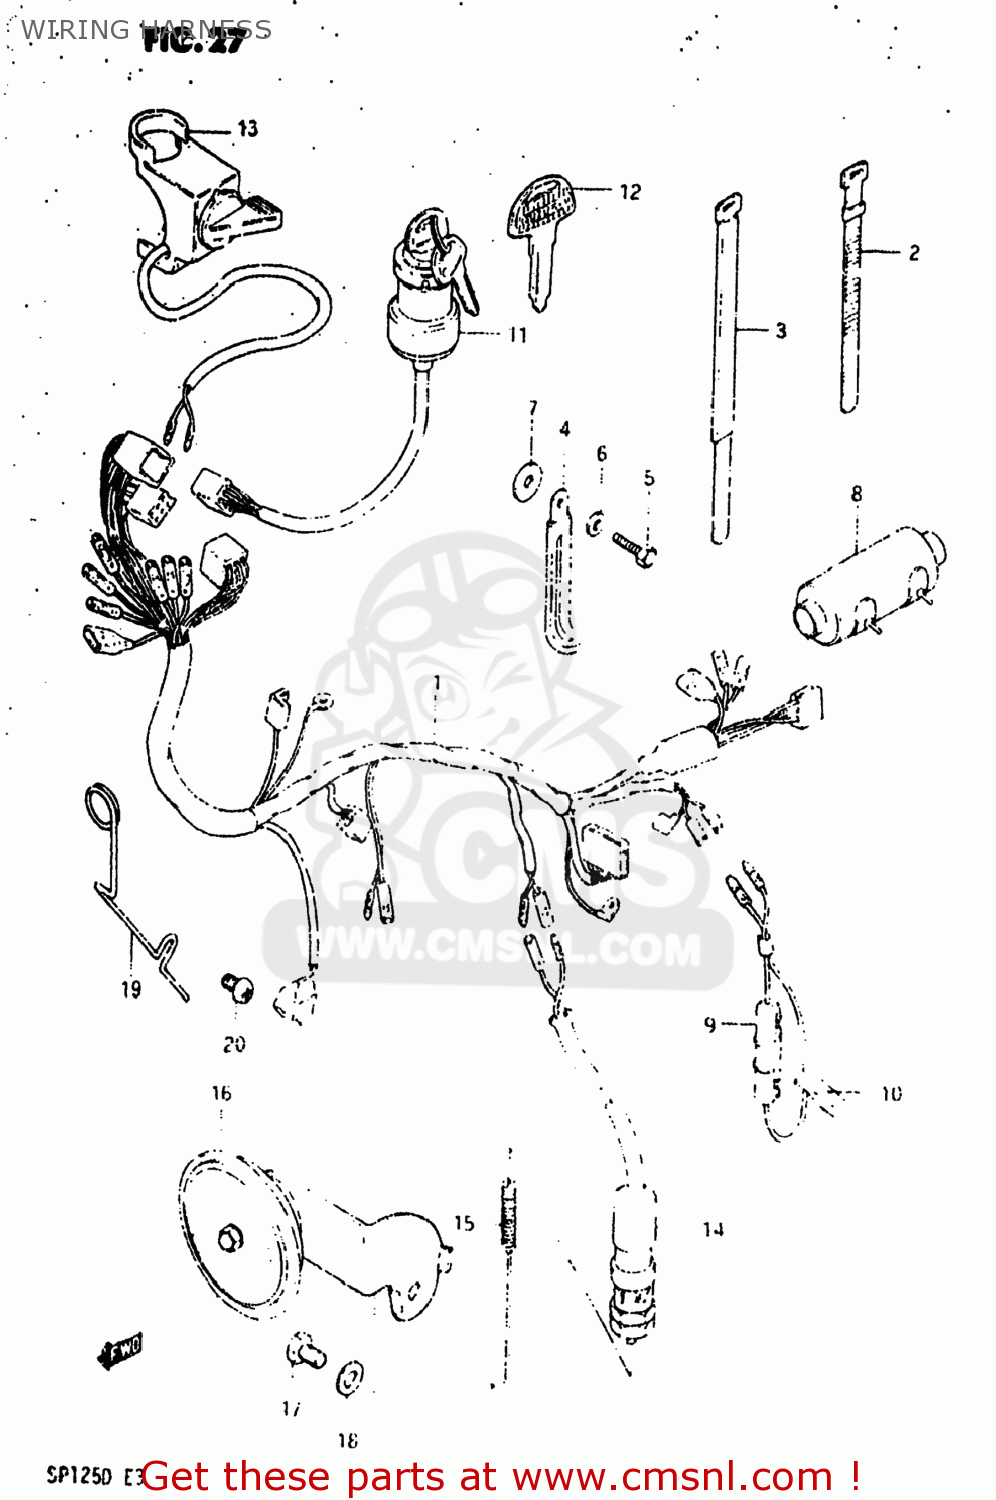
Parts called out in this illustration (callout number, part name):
1	HARNESS,WIRING
2	CLAMP(L:120)
3	CLAMP
4	CLAMP
5	BOLT, UPPER
6	WASHER
7	WASHER
8	BOOT,WIRING HARNESS
9	BOX ASSEMBLY,FUSE
10	FUSE(15A)
11	SWITCH ASSEMBLY,IGNITION
12	KEY,BLANK
13	SWITCH ASSY,ENGINE STOP
14	SWITCH ASSEMBLY,STOP LAMP
15	SPRING
16	HORN ASSEMBLY
17	BOLT
18	WASHER
19	GUIDE,TACHOMETER CABLE
20	SCREW, FRONT
